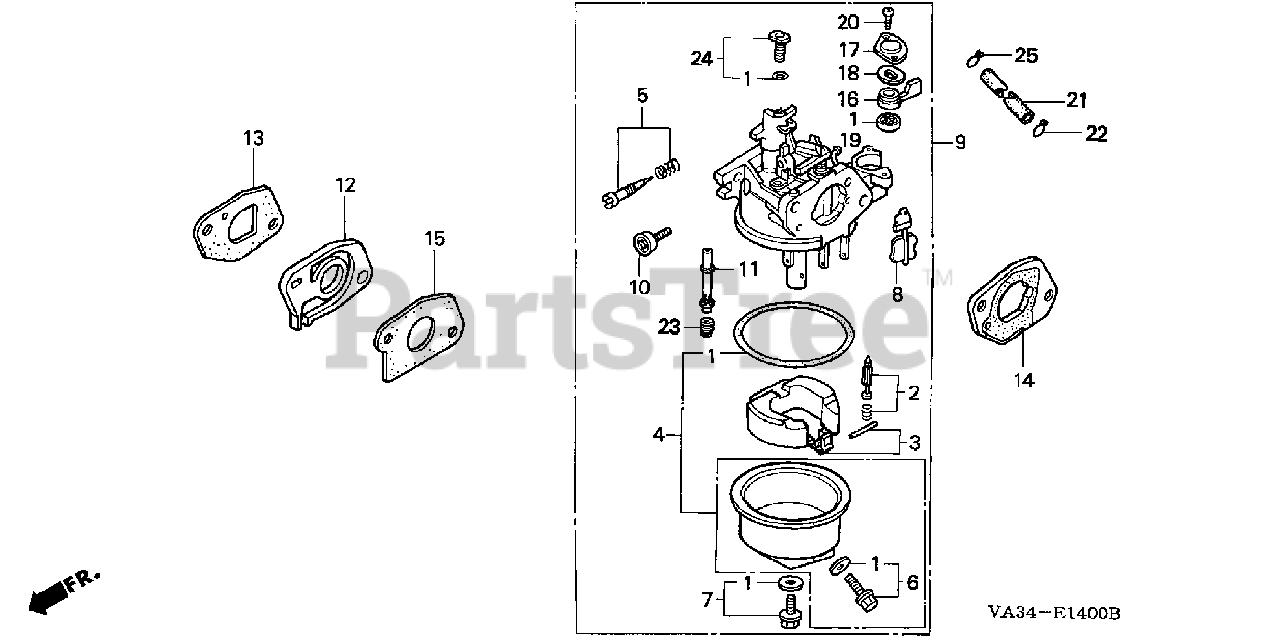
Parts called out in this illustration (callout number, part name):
1	GASKET SET
2	VALVE SET, FLOAT
4	CHAMBER SET, FLOAT
5	SCREW SET, PILOT
6	SCREW SET, DRAIN
7	SCREW SET
9	CARBURETOR ASSY. (BE46B A)
10	SCREW, THROTTLE STOP
11	NOZZLE, MAIN
12	INSULATOR, CARBURETOR
13	GASKET, CARBURETOR
14	SPACER, CARBURETOR
15	GASKET, CARBURETOR
16	LEVER, VALVE
17	PLATE, LEVER SETTING
18	SPRING, PETCOCK LEVER
19	GASKET, PETCOCK
20	SCREW, PAN (3X6)
20	SCREW, PAN (3X8)
23	JET, MAIN (#58)
23	JET, MAIN (#62)
23	JET, MAIN (#60)
24	JET SET, PILOT (#35)
